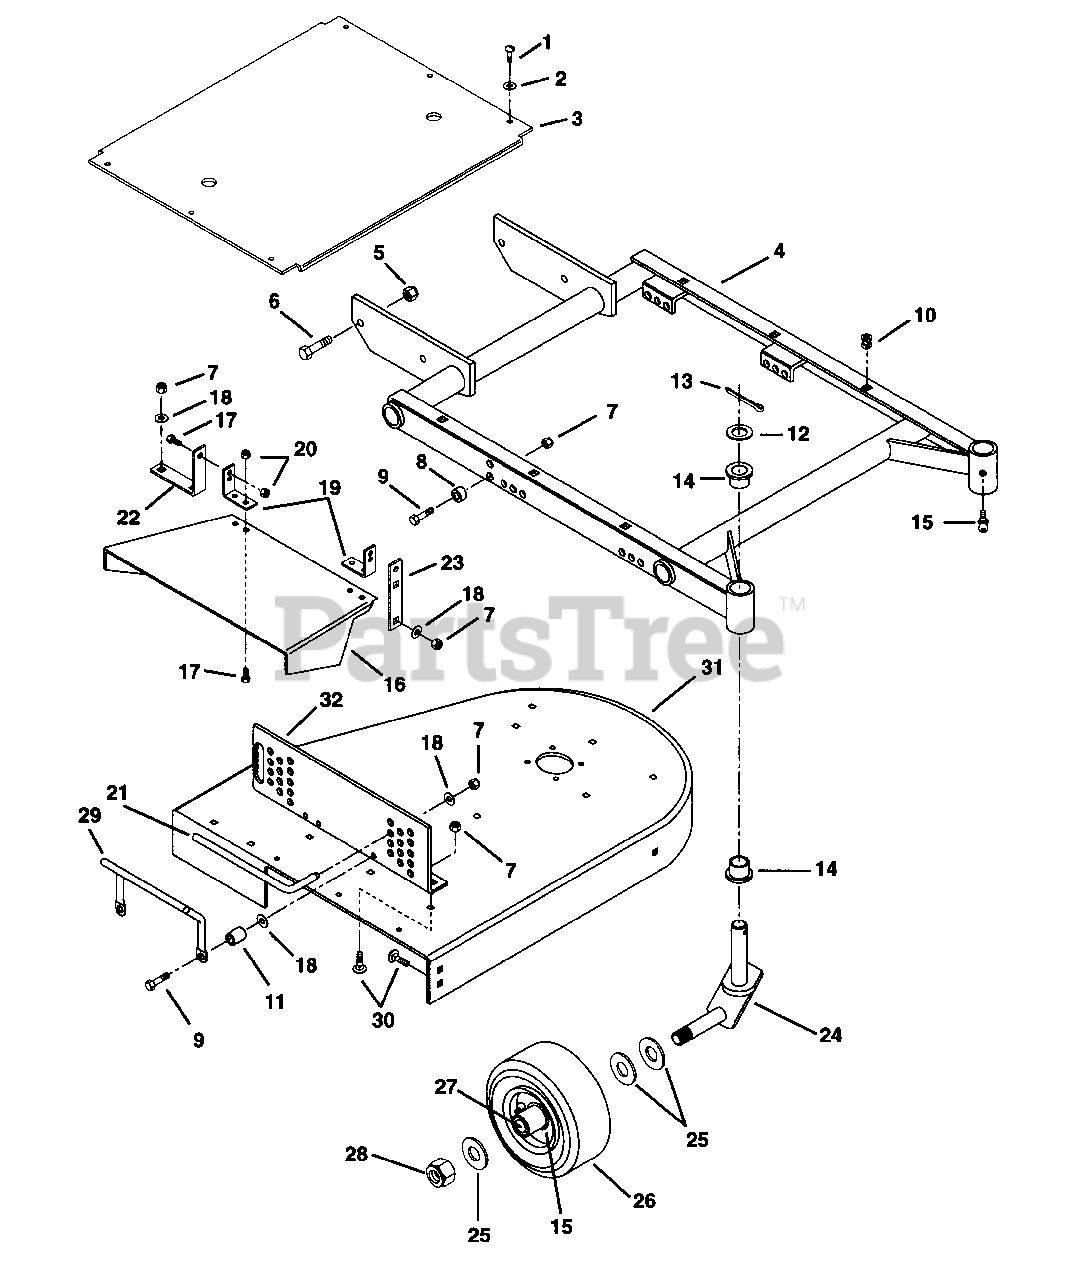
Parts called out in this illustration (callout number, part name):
1	Screw-Tapping .25-20 x .50
2	Washer-Flat-Steel .281 x .625 x .065
3	Cover, Silkscreen
4	Weldment, Mower Frame
5	Nut-Locking-Nylon .625-11 Grade 2
6	Bolt-Hex .62-11 x 1.50
7	Nut-Locking-Nylon .375-16 Grade 2
8	Bushing .391 x .626 x .670
9	Bolt-Hex .38-16 x 1.50 Grade 5
10	Grommet, Plastic
12	Washer-Hardened-Thrust 1.002 x 1.552 x .030
13	Pin-Cotter .188 x 1.50
14	Bushing-Flange 1.020 x 1.385 x .75 x 1.75
15	Fitting-Lube .25-28 x .256
16	Chute, Discharge
17	Bolt-Hex .31-18 x .75 Grade 5
18	Washer-Flat-Steel .406 x .812 x .065
20	Nut-Locking-Nylon .312-18 Grade 2
21	Pin, Mower Locking
24	Weldment, Castor Fork
25	Washer-Flat .812 x 1.469 x .134
26	Wheel 9 x 3.50
27	Bearing, Gauge Wheel
28	Nut-Locking-Nylon .75-10 Grade 2
30	Bolt-Round Head Square Neck .38-16 x 1.0
31	Weldment, 36" Deck
32	Bracket, Mower Side Support Left Hand
